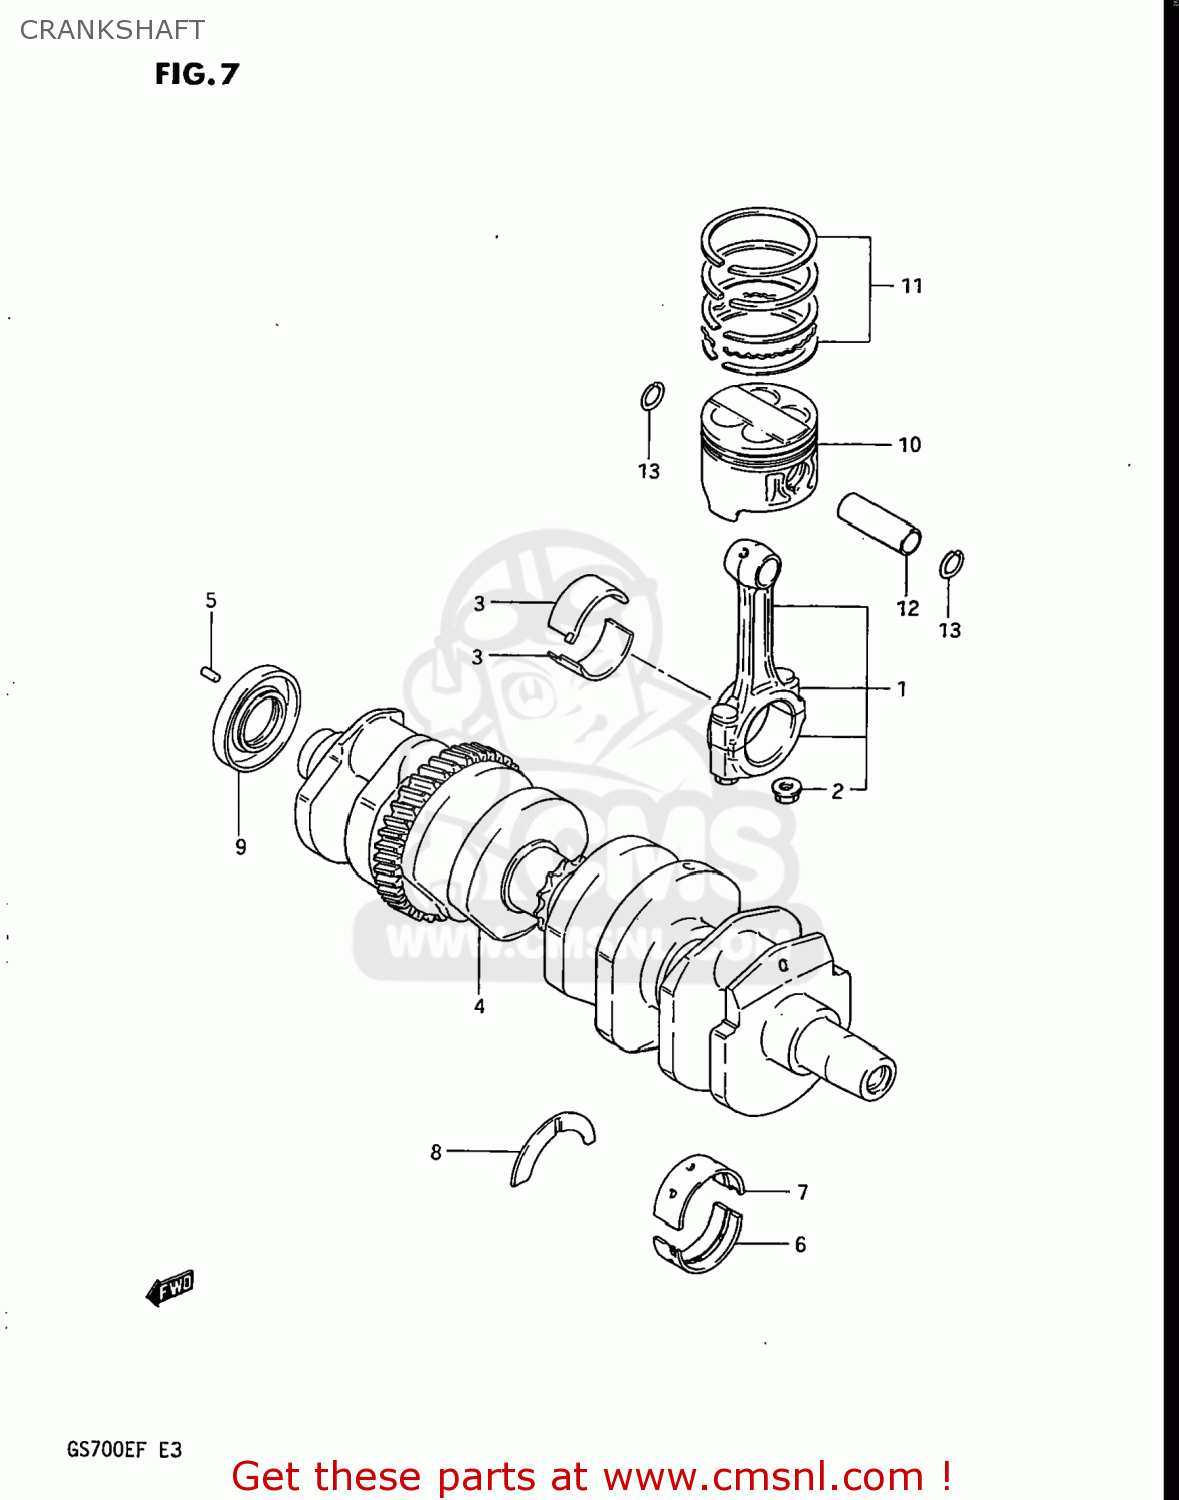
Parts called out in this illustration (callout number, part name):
1	CONNECTING ROD ASSEMBLY
2	NUT
3	METAL,CRANK PIN
4	CRANKSHAFT
5	PIN
6	METAL,CRANKSHAFT (GREEN)
7	METAL CRANKSHAFT (GREEN)
8	PLATE,CRANK THRUST
9	SEAL,OIL(30X60X8)
10	PISTON (STD)
11	RING SET,PISTON
12	PIN,PISTON
13	CIRCLIP
